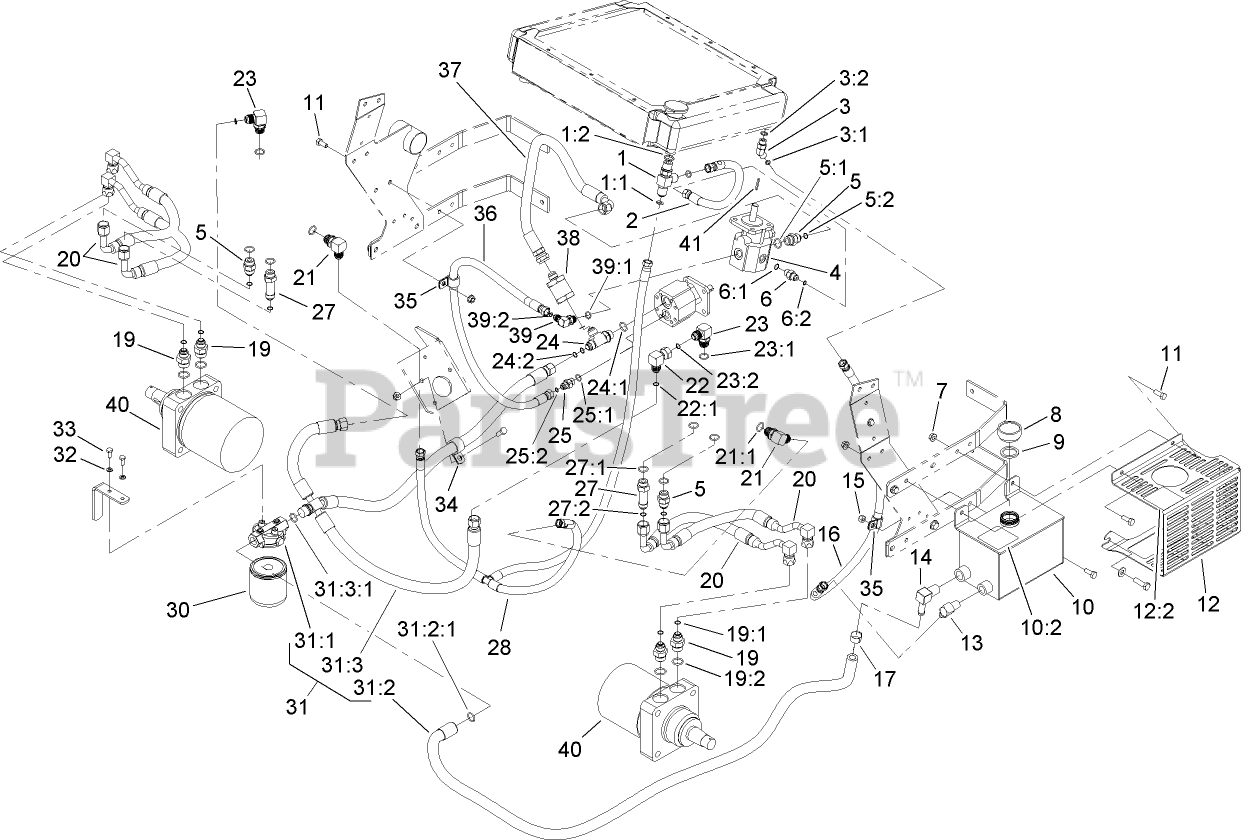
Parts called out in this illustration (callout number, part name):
1	FITTING-HYD, STRAIGHT TEE
1:1	O-RING
1:2	O-RING
2	FAN CASE DRAIN HOSE ASM
3	FITTING-HYD, 45 ELBOW
3:1	O-RING
3:2	O-RING
4	MOTOR-FAN, COOLING
5	FITTING-STRAIGHT
5:1	O-RING
5:2	O-Ring
6	FITTING-STRAIGHT
6:1	O-RING
6:2	O-RING
7	NUT-HF
9	GASKET-CAP, TANK
10	HYD TANK ASM
10:2	DECAL-TANK, HYD
11	SCREW-HH
12	HYDRO TANK SHIELD ASM
12:2	DECAL-SURFACE, HOT (CE)
13	FITTING-ELBOW, 90 DEG
14	FITTING-90 DEG
15	NUT-LOCK, NI
16	TANK RETURN HOSE ASM
17	CLAMP-HOSE
19	Fitting-Straight
19:1	O-RING
19:2	O-Ring
20	HYD HOSE ASM
21	FITTING-ELBOW, 90 DEG
21:1	O-RING
22	FITTING-90 DEG
22:1	O-Ring
23	FITTING-90 DEG
23:1	O-RING
23:2	O-Ring
24	FITTING-TEE
24:1	O-RING
24:2	O-Ring
25	FITTING-STRAIGHT
25:1	O-Ring
25:2	O-RING
27	ADAPTER-HYD, STRAIGHT
27:1	O-RING
27:2	O-Ring
28	CASE DRAIN HOSE ASM
30	CARTRIDGE-FILTER, OIL
31	CHARGE HOSE ASM
31:1	HEAD-FILTER
31:2	FILTER INLET HOSE ASM
31:2:1	O-RING
31:3	PUMP INLET HOSE ASM
31:3:1	O-RING
32	WASHER-LOCK
33	SCREW-HH
34	CLIP-LOOM
35	CLIP-LOOM
36	AUXILLARY PUMP HOSE ASM
37	HOSE-PRESSURE, HIGH
38	FILTER-IN LINE, 50 MICRON
39	FITTING-90 DEG
39:1	O-Ring
39:2	O-RING
40	MOTOR-WHEEL, HYD
41	KEY-SQUARE
